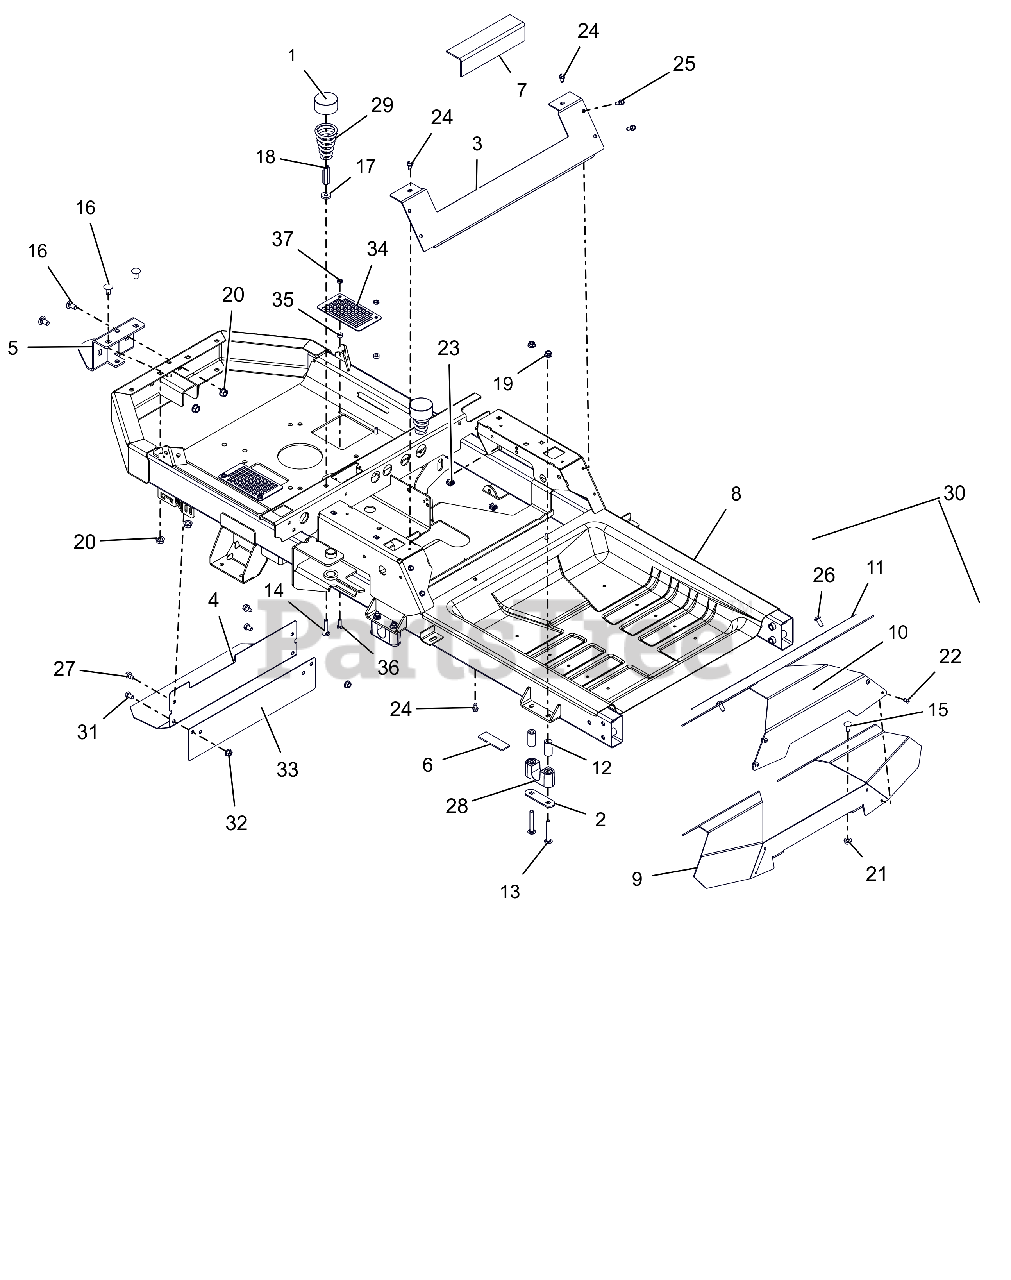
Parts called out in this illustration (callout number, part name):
1	HUB CAP
2	PLATE, BEARING SUPPORT
3	PLATE, SEAT KICK
4	HEAT, SHIELD
5	BRKT, HITCH TONGUE
6	PAD,RBR 1.0"X3.0" W/ADHESIVE
7	PAD, RUBBER-TANK
8	WLDMT, FRAME -IKON X/XL ARIENS
9	PLATE,FOOT
10	PLATE,FOOT
11	GRIP TAPE, FOOT PLATE
12	SPACER, .323 X .698 X 1.441
13	BLT-RDHDSQSHNK .31-18X2.25 YWZ
14	@BLT-RDHDSQNK .31-18X1.50 G5YZ
15	@BLT-RDHDSQNK .31-18X.75 G5YZ
16	@BLT-RDHDSQNK .38-16X.75 G5YZ
17	WSHR-FL-STL .328X.87X.179 YWZC
18	NUT, COUPLING 5/16-18 X 1 3/4
19	@NUT-LK-CTR-FLG .31-18 YZ GR F
20	@NUT-LK-TOP-FLG .38-16 YWZC
21	@NUT-LK-TOP-FLG .31-18 YWZC
22	RIVET, #66 STEEL POP PD BLACK
23	NUT RETNR .25-20
24	SCR-TAP .25-20X.50 HWH TR YWZ
25	SCR-TAP-PM .25-20X.75 TR YWZ
26	SCR-RDHDSKTAP .31-18 X .75
27	@SCR-TAP .31-18X.50 HWH TR YWZ
28	BSHG, DECK LIFT PIVOT
29	SPRING, SEAT
30	KIT, IKON FOOT REST W/DECAL
31	@BLT-HEX .31-18X.50 GR5 YWZC
32	@NUT-LK-TOP-FLG .31-18 YWZC
33	GUARD, REAR CLUTCH
34	GUARD, VENT - IKON CE
35	BSHG-SLV .265X.500X.219
36	@BLT-HEX .25-20X.75 GR5 YWZC
37	NUT-LK-CTR JAM .25-20 YWZC
